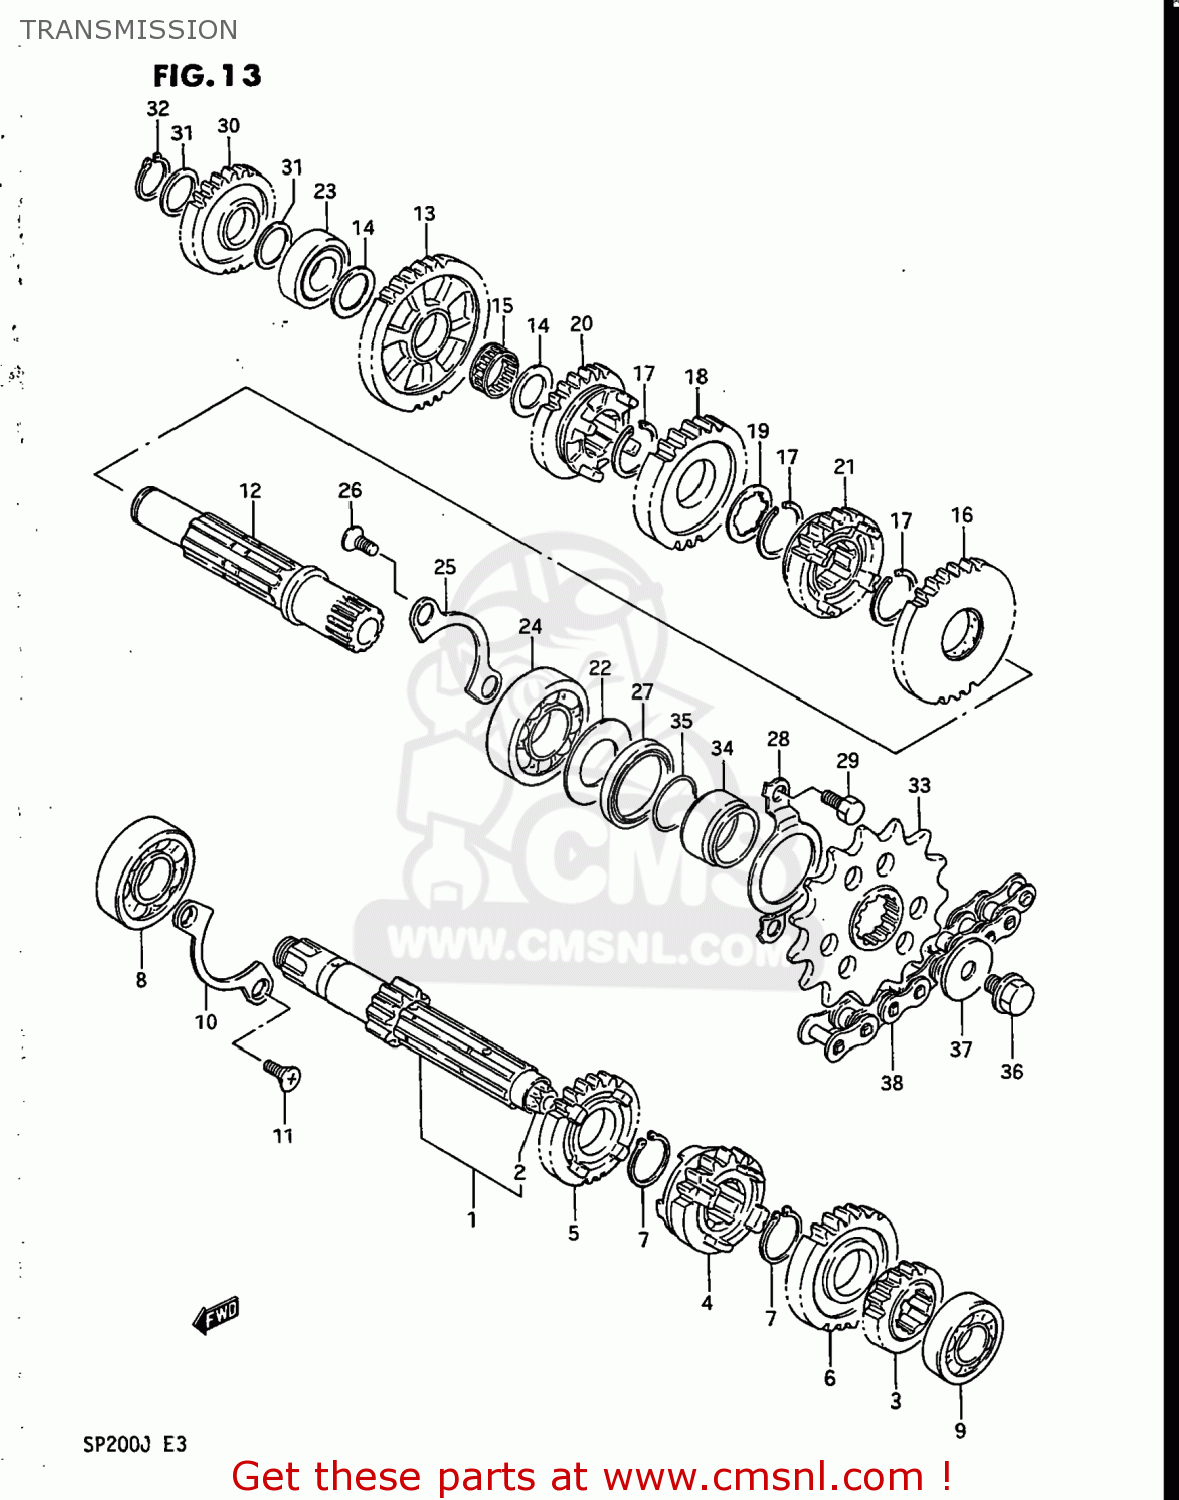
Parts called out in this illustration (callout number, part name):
1	SHAFT,COUNTER (NT:11)
2	BUSH
3	GEAR,2ND DRIVE
4	GEAR,THIRD DRIVE (NT:16)
5	GEAR,4TH DRIVE
6	GEAR,FIFTH DRIVE
7	CIRCLIP
8	BEARING
9	BEARING, LH
10	RETAINER,DRIVE SHAFT BEARING
11	SCREW
12	SHAFT COMP,DRIVE
13	GEAR,1ST DRIVEN
14	WASHER,THRUST
15	BEARING(17X21X9.8)
16	GEAR,SECOND DRIVEN (NT:29)
17	CIRCLIP
18	GEAR,THIRD DRIVEN (NT:23)
19	WASHER,LOCK
20	GEAR,FOURTH DRIVEN (NT:23)
21	GEAR,5TH DRIVEN
22	WASHER,OIL SEALING
23	BEARING(17X36X12)
24	BEARING(22X50X14)
25	RETAINER,DRIVE SHAFT BEARING
26	SCREW
27	SEAL,OIL(30X40X6)
28	RETAINER,DRIVESHAFT O
29	BOLT
30	GEAR,KICK STARTER IDLE
31	WASHER
32	CIRCLIP
33	SPROCKET,ENGINE
34	SPACER,ENGINE SPROCKET
35	O RING(D:2.5,ID:21)
36	BOLT
37	WASHER
38	CHAIN ASSEMBLY,DRIVE
